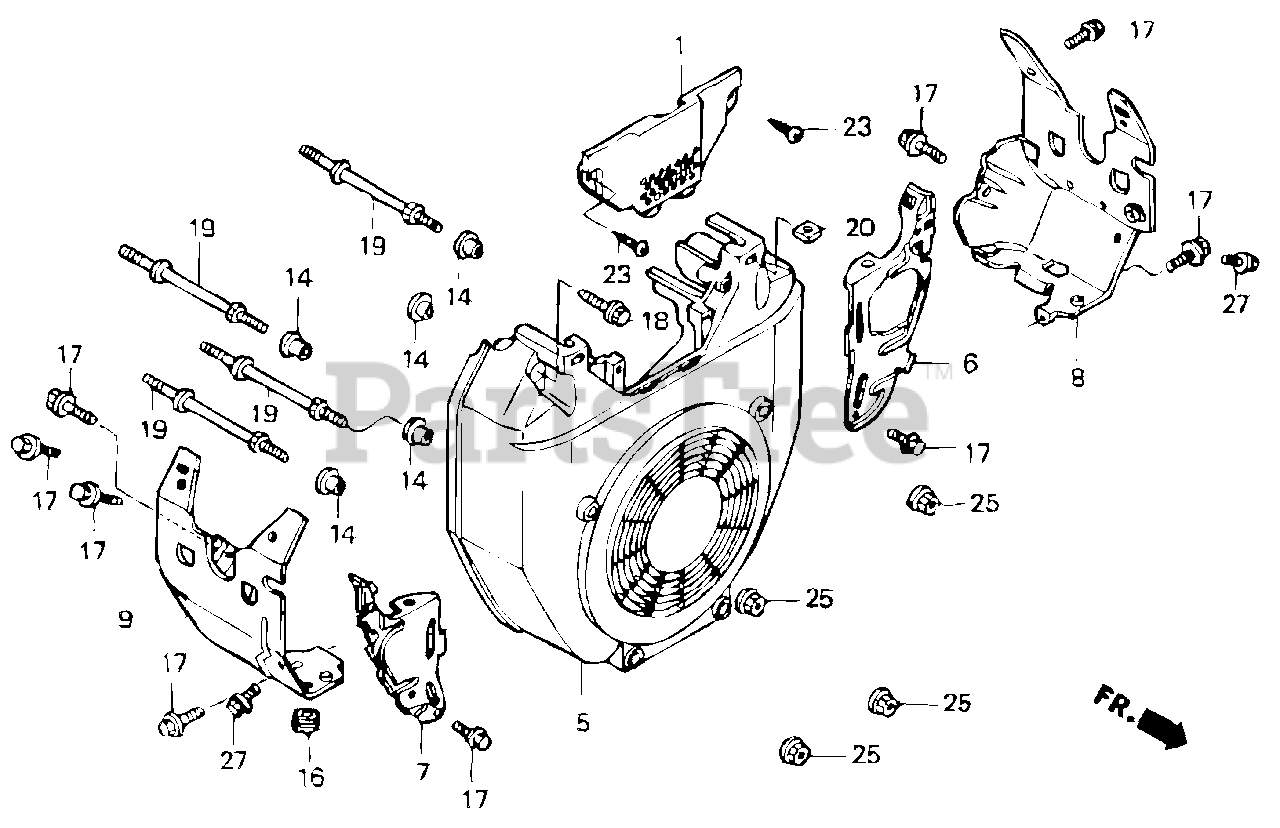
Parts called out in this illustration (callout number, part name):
1	Cover, Fuel Pump
5	Cover, Fan (Bright Red)
6	Plate, R. Side
7	Plate, L. Side
9	Shroud, L
14	Collar B, Taillight
16	Rubber, Rr. Fender Cushion
17	Bolt, Flange (6x12) (Ct200)
18	Bolt, Flange (6x23)
19	Bolt, Stud (6x71)
20	Nut, Square (5mm)
23	Screw, Tapping (5x20)
25	Nut, Flange (6mm)
27	Bolt, Flange (6x8)
